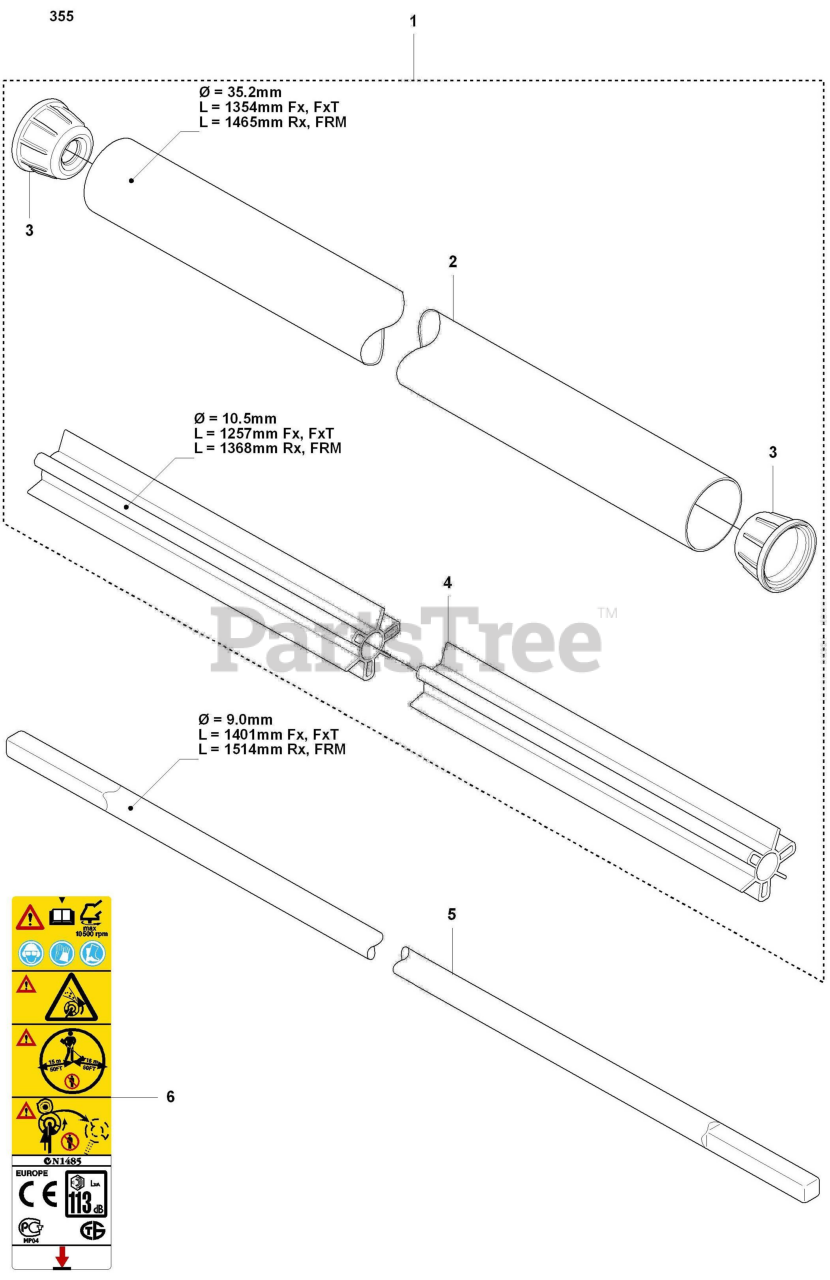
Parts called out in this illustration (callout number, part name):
1	TUBE ASSY
2	TUBE
3	RP SPACER
4	RP BEARING SHAFT
4	%BEARING SHAFT
5	DRIVE SHAFT
